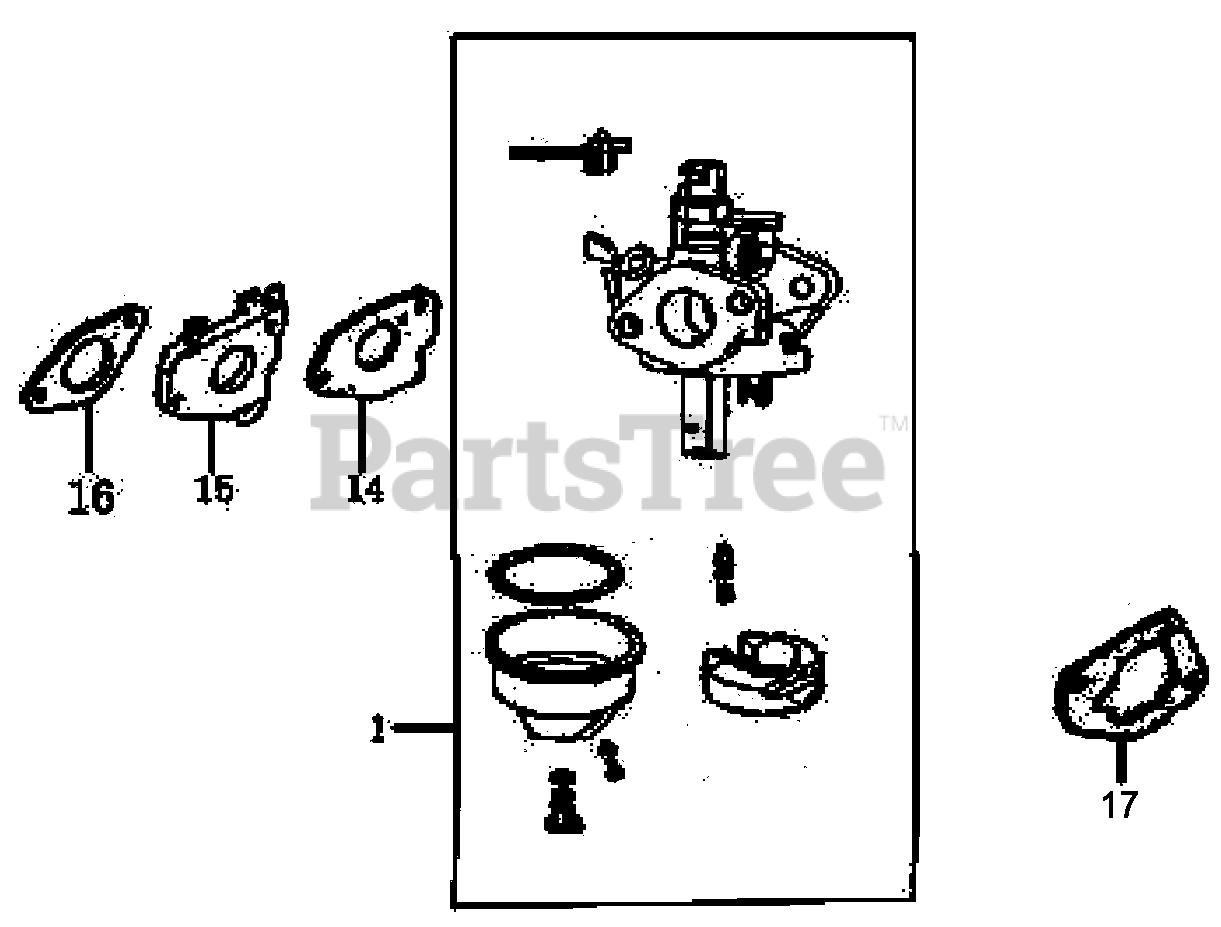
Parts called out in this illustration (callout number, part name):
1	CARBURETOR
14	GASKET, CARBURETOR
15	INSULATOR, CARBURETOR
16	GASKET, INSULATOR
17	GASKET, CARBURETOR
